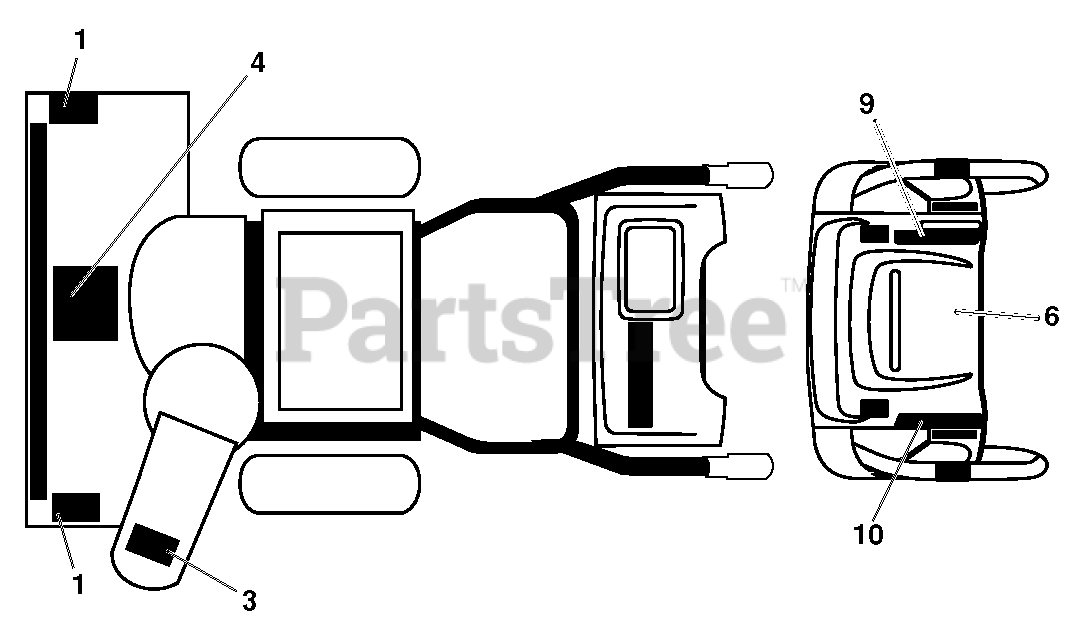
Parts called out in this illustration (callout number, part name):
1	DECAL.SNOWTHR.AUGER
3	DECAL.SNOWTHR.CHUTE.SAFETY
4	DECAL.SNOWTR.READ.OWN.MAN.E/F
6	DECAL.CONSOLE.SNOW.INST.ENG/FR
9	DECAL.CONS.RT.SPD/LEV/PWRST.
10	DECAL.CONS.LT.SPD/LEV/PWRST.
